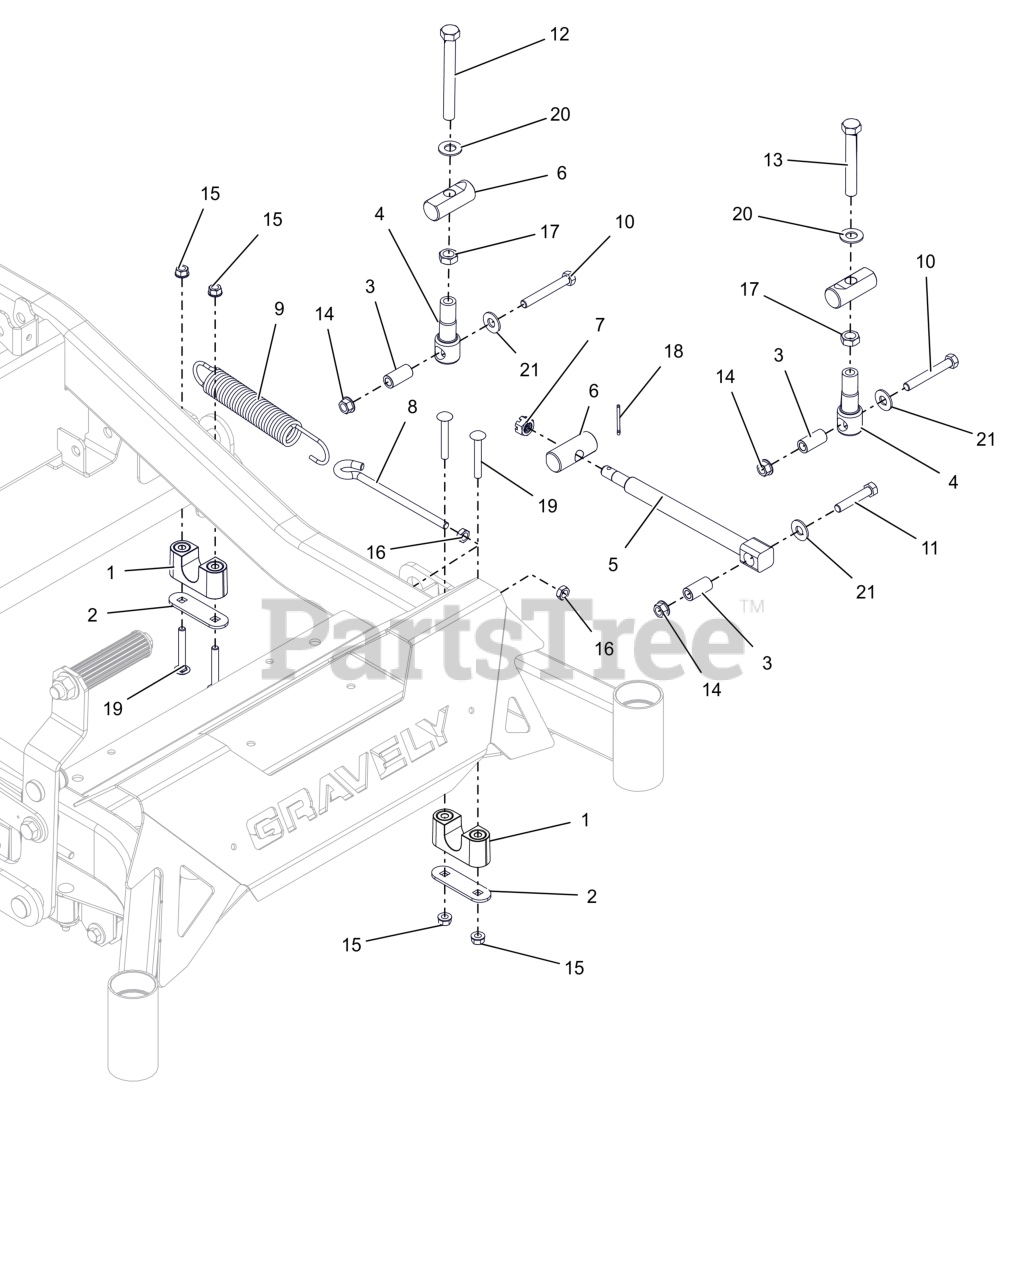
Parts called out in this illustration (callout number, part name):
1	ASM-BUSHING, DECK LIFT
2	PLATE, BEARING SUPPORT
3	SPACER, DECK LEVELING
4	LINK, DECK LIFT FORMED
5	DRAG,LINK-HD
6	PIN, DECK LIFT
7	NUT-SL .50-13
8	BOLT,.38-16 X 5.25-.62 DIA EYE
9	SG-TENS .162X1.25X8.25 WLD 25
10	BLT, HEX .38-16X2.75 G8 ZCC
11	BLT,HEX .38-16X2.00 G5 ZCC
12	BLT, HEX .50-13X4.50F G8 ZCC
13	BLT, HEX 0.5-13X3.5F GR5 ZCC
14	NUT-LK-TOP-FLG .38-16 ZC120
15	NUT,LK-CTR-FLG .31-18 GF ZCC
16	NUT-JAM .375-16 G2 ZCC
17	NUT-JAM .500-13 G2 ZCC
18	PIN,CTR.12X1.25EXTPRSQCT ZC120
19	BLT, RHSSN.31-18X2.25 G5 ZCC
20	WSHR, FLT .557X1.040X.102 ZCC
21	WSHR,FLT .438X1.00X.083 ZCC
